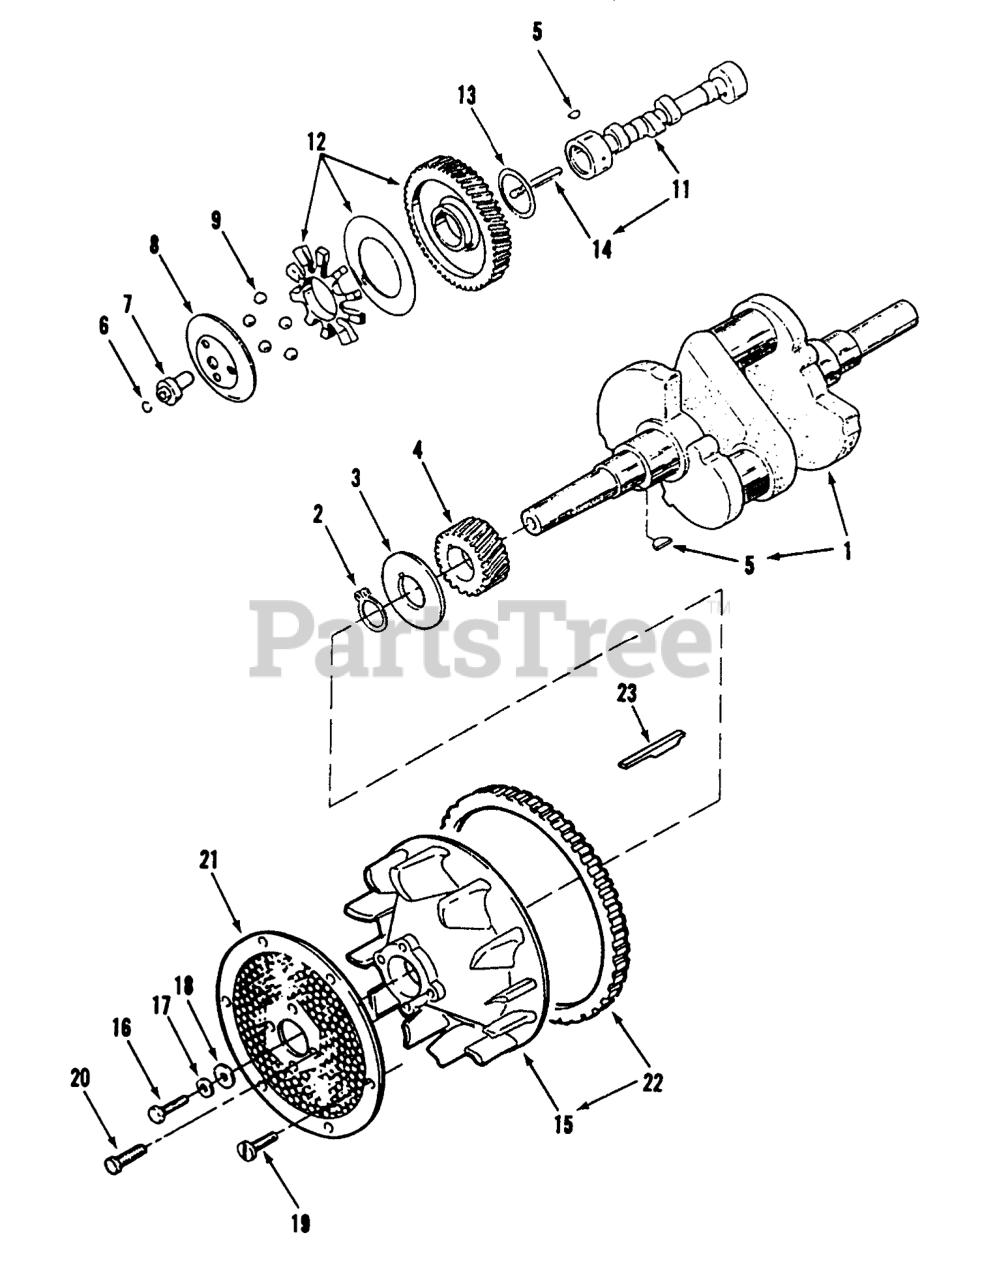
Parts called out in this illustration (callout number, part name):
1	CRANK-SHAFT
3	WASHER
7	HUB-GOVERNOR CUP
8	CUP-GOVERNOR
9	BEARING
11	Camshaft (Incl. Item 13)
12	Camshaft Gear (Incl. Gear, Spacer, & Plate)
13	WASHER-THRUST
14	PIN-CENTER
15	Flywheel (Incl. Ring Gear)
16	SCREW
17	WASHER-FLAT
18	WASHER-FLAT
19	LOCK SCREW
20	SCREW - CAP HEX HEAD
21	Screen
23	KEY - MACHINE
